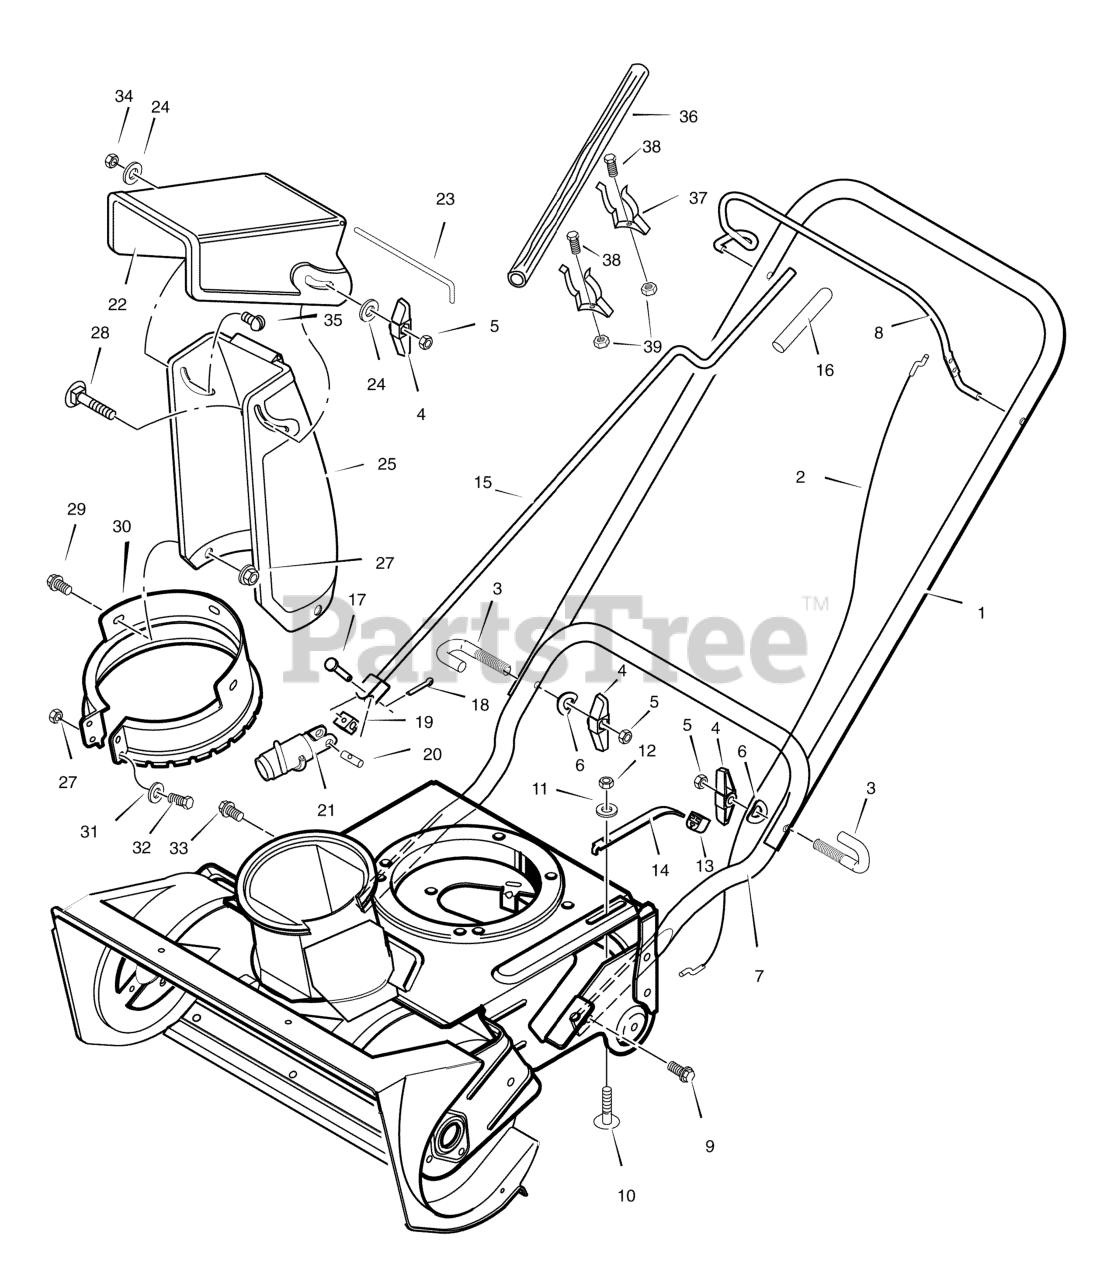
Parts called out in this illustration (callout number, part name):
1	Handle, Upper
2	Cable, Auger Drive
4	Knob
5	Nut
7	Handle, Lower
8	Lever, Auger Drive
9	Screw
13	Bushing, Tensioner
14	Bracket, Cable Tensioner
15	Rod, Crank
16	Grip, Crank Rod
17	Pin, Clevis
18	Pin, Cotter
19	Block, Universal Pivot
21	Gear, Worm
22	Chute, Upper Deflector
23	Pin, Pivot
24	Washer
25	Chute, Lower Discharge
30	Ring, Chute
31	Washer
33	Screw
34	Locknut
36	Tool, Clean-out
37	Clip, Retainer
38	Screw, 10-32 x 1.25
39	Nut, 10-32
